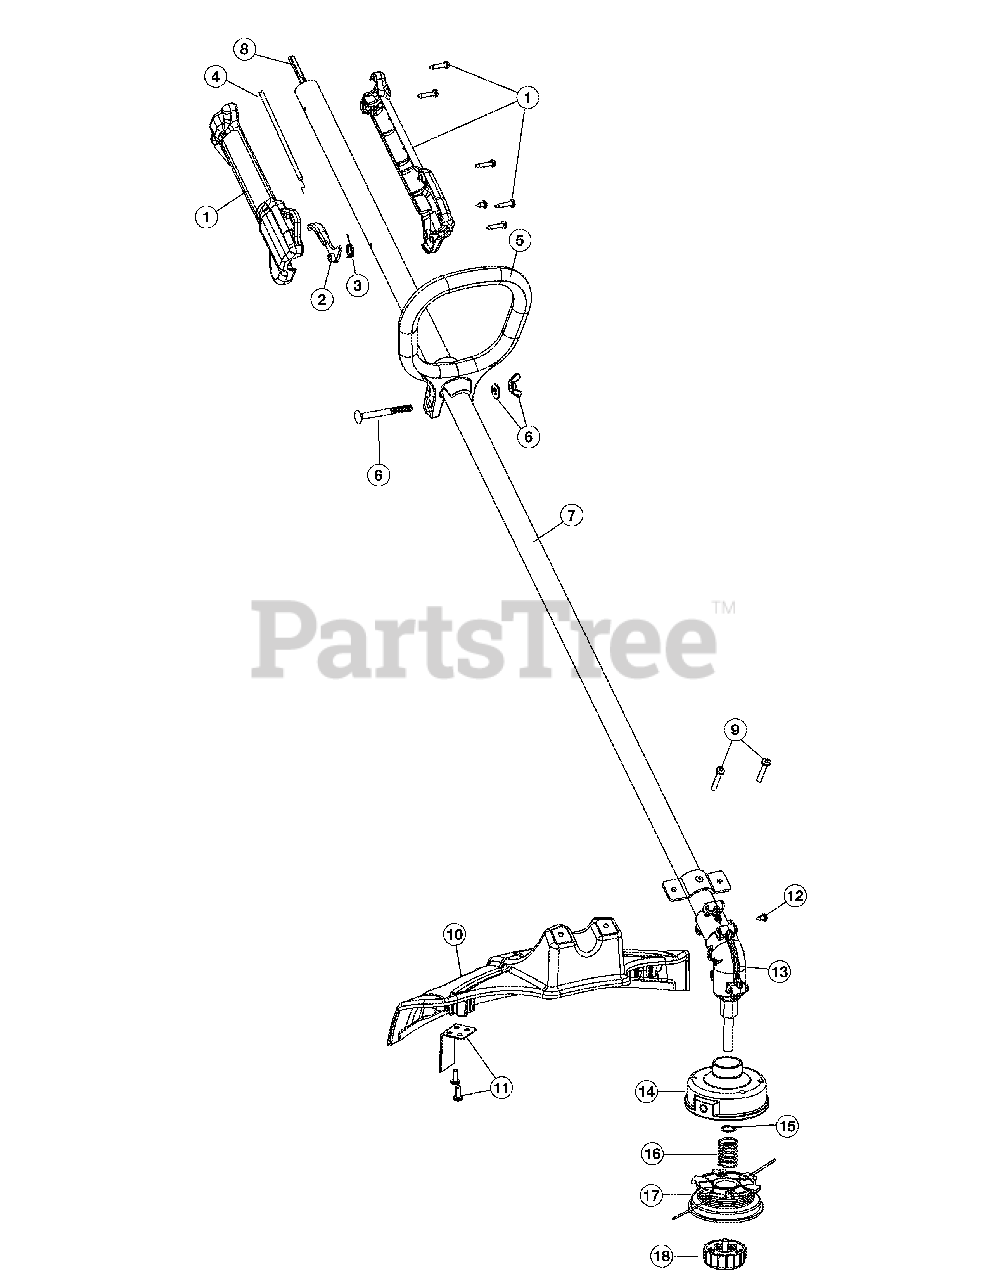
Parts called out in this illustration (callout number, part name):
1	Throttle Housing Assembly (Incl. Ref No. 2 & 3)
2	Throttle Trigger Spring
3	Throttle Trigger
4	Throttle Cable
5	D-Handle Assembly (Incl. Ref No. 6)
6	D-Handle Hardware
7	Drive Shaft Housing Assembly
8	Flexible Drive Shaft
9	Shield Mounting Hardware
10	Shield Assembly (Incl. Ref No. 11)
11	Blade Assembly
12	Anti-Rotation Screw
13	Gearbox Assembly
14	Outer Spool Assembly (Incl. Ref No. 15)
15	Retainer
17	Inner Reel
18	Bump Head Knob Assembly
